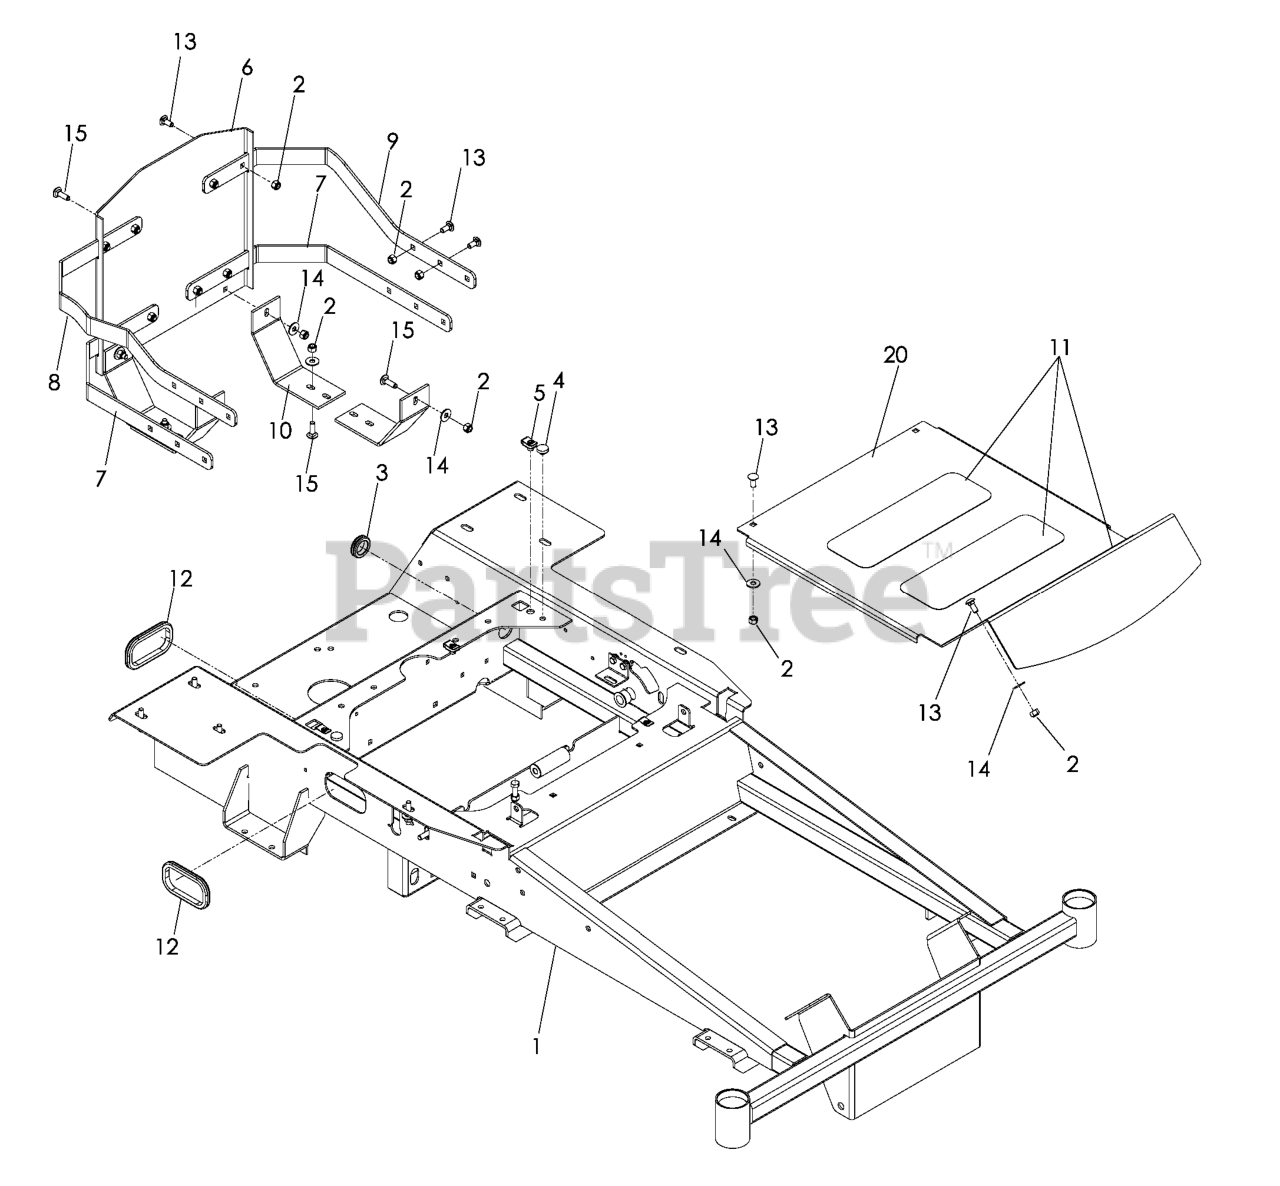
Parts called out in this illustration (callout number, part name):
1	FRAME W/DECALS #
2	NUT 5/16 NYLOC
3	RUBBER GROMMET
4	GROMMET, BUMPER
5	U-CLIP 5/16-18 NUT RETAINER
6	ENGINE GUARD
7	REAR GUARD STRAP, LOWER
8	REAR GUARD STRAP, UPPER RIGHT
9	REAR GUARD STRAP, UPPER LEFT
10	SKID PLATE
11	ANTI-SKID PAD
13	BOLT 5/16C X 3/4" CARRIAGE
14	WASHER 5/16 FLAT
15	RHSNB 5/16C X 1
